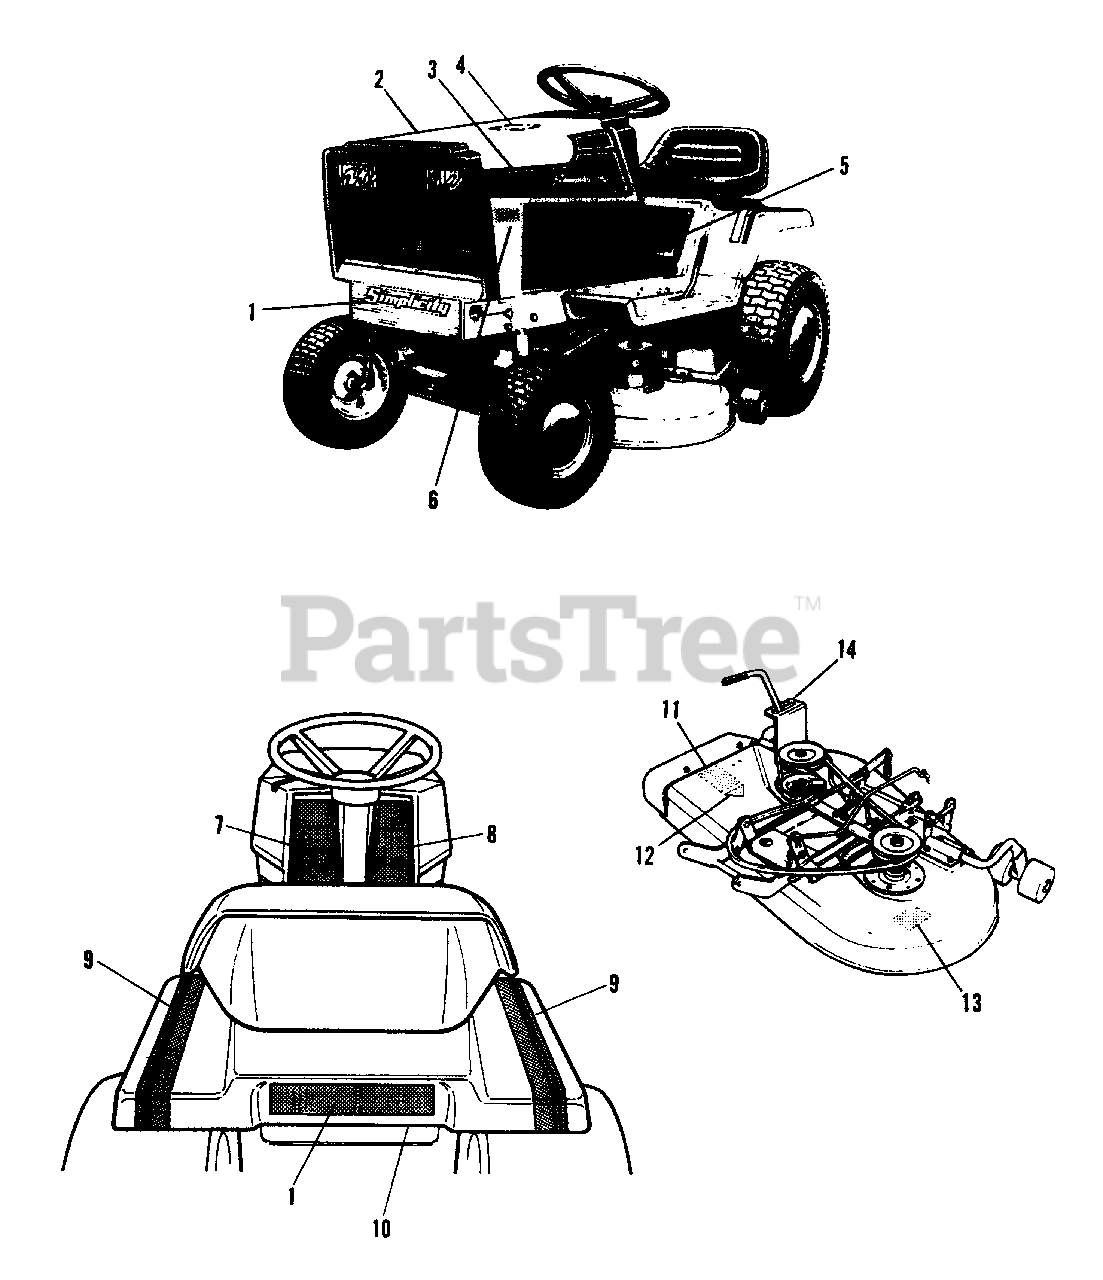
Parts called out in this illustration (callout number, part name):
1	DECAL, Simplicity
2	DECAL, Hood, R.H.
3	DECAL, Hood, L.H.
4	DECAL, Drive Belt
5	DECAL, Shift Pattern
6	DECAL, 4208 Electric
6	DECAL, 4211 Electric
7	DECAL, Dash, L.H. Side
8	DECAL, Dash, R.H. Side (1690840, 1690843 only)
8	DECAL, Dash, R.H. Side (1690909 only)
9	DECAL, Seat Deck
10	DECAL, Battery, Simplicity
11	DECAL, Warning
12	DECAL, OPEI
13	DECAL, Danger
14	DECAL, Mower Height
